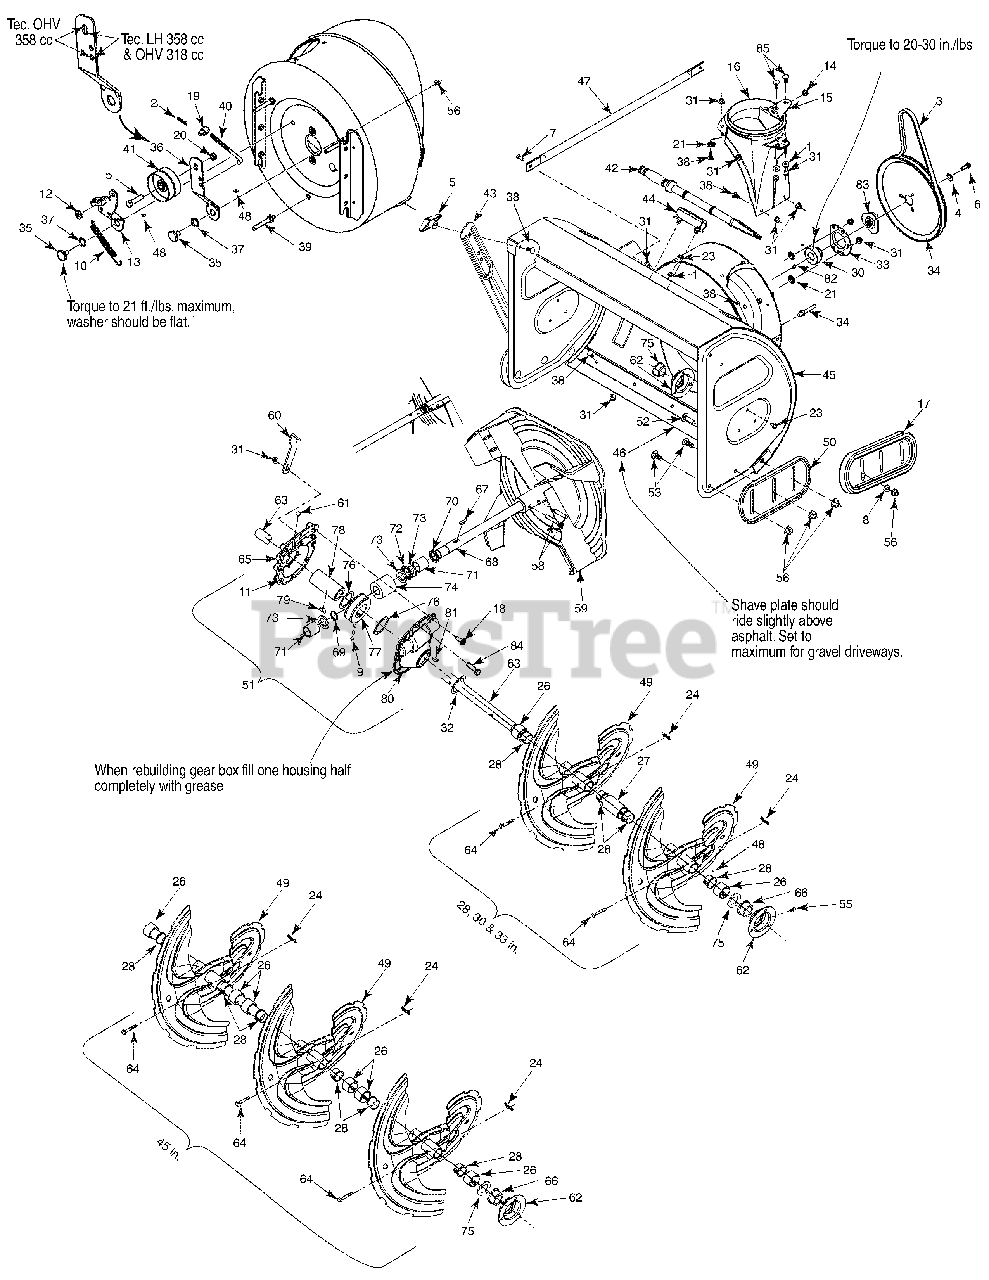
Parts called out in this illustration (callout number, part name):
1	Flat Washer .349 ID x .879 OD x .063
2	Int. Cotter Pin
3	V-Belt 1/2 x 44" Lg.
3	V-Belt 1/2 x 42" Lg.
4	Flat Washer .34 x 1.5 x .150
5	Handle Knob Assembly
6	Hex Screw 5/16-24 x .875 Gr. 8 Lock
7	Hex Hd Cap Scr. 5/16-18 x .75 Gr. 5
8	Flat Washer .385 x .870 x .092
9	Shell Alvania Grease (3 oz.)
10	Extension Spring .470 Dia. x 4.75
11	Ultra Grey Loctite #5699
12	Flat Washer .344 ID x .75 OD x .120
13	Brake Bracket Ass’y (900 Series)
14	Plastic Bushing .380 ID
15	Chute Brkt.
16	Chute Adapter
17	Reversible Slide Shoe (Plastic)
18	Screw, 5/16-18 x .5
19	Adjustment Ferrule
21	Push-on Nut .25 diam
23	Hex TT Screw 3/8-16 x .75
24	Bow Tie Cotter Pin
26	Spacer 1.5 x 1.0 ID x 1.0" Lg.
27	Spacer 1.5 x 1.0 ID x 2.5" Lg.
28	Flange Bushing 1.05 ID x 1.16 OD
30	Self-Aligning Bearing .875 ID
31	Hex Flg. L-Nut 5/16-18 Gr. F Nylon
32	Flat Washer 1.010 x 1.88 x .060
33	Bearing Housing
34	Pulley .5 ID x 10 OD
35	Shoulder Scr .625 Dia x .170
36	Auger Idler Bracket
37	Wave Washer .625 ID x .885 OD x .015
38	Carriage Bolt 5/16-18 x .75
39	Screw 5/16-18 x .43
40	Auger Idler Rod
41	Flat Idler Pulley
42	Cleanout Tool
44	Cleanout Tool Mount
51	Worm Gear Box Ass’y
52	Carriage Bolt 3/8-16 x 1.00" (w/steel shoe)
52	Carriage Bolt 3/8-16 x 1.25" (w/plastic shoe)
53	Carriage Bolt 3/8-16 x .75" (w/steel shoe)
53	Carriage Bolt 3/8-16 x 1.00" (w/plastic shoe)
56	Hex Flange L-Nut 3/8-16 Gr. F Nylon
58	Spring Spirol Pin Heavy - 5/16 dia x 1.7
60	Gear Housing Support Bracket
61	Barbed Plug
62	Bearing Housing (w/grease fitting)
63	33'' Auger Shaft
63	45'' Auger Shaft
64	Shear Pin 5/16-18 x 1.75
65	Gear Housing Half - RH
66	Flange Bearing
67	#9 HI-Pro Key 3/16 x 3/4 Dia HT
68	Auger Drive Shaft
69	Snap Ring for .875 dia. shaft
70	Oil seal for .875 ID Garlock (76 x 6133)
71	Sleeve Bearing .875 ID
72	Thrust Bearing .88 ID x 1.44 OD x .078
73	Flat Washer .88 ID x 1.4 OD x .125
74	Worm Gear LH Double Thread
75	Spacer
76	Flat Washer 1.5 ID x 2.0 OD x .03
77	Worm Gear LH Double Thread (Bronze)
78	Worm Gear Shaft
79	#91 Woodruff Key 1/4 x 3/4 Dia.
80	Gear Housing Half LH
80	Gear Housing Half LH (w/grease fitting hole)
81	#91 Woodruff Key 1/4 x 3/4 Dia.
82	LowTemperature grease
83	Pulley Adapter .75 Dia. w/pins
84	Hex Hd. Cap Scr. 5/16-18 x 1.0 Gr. 5
